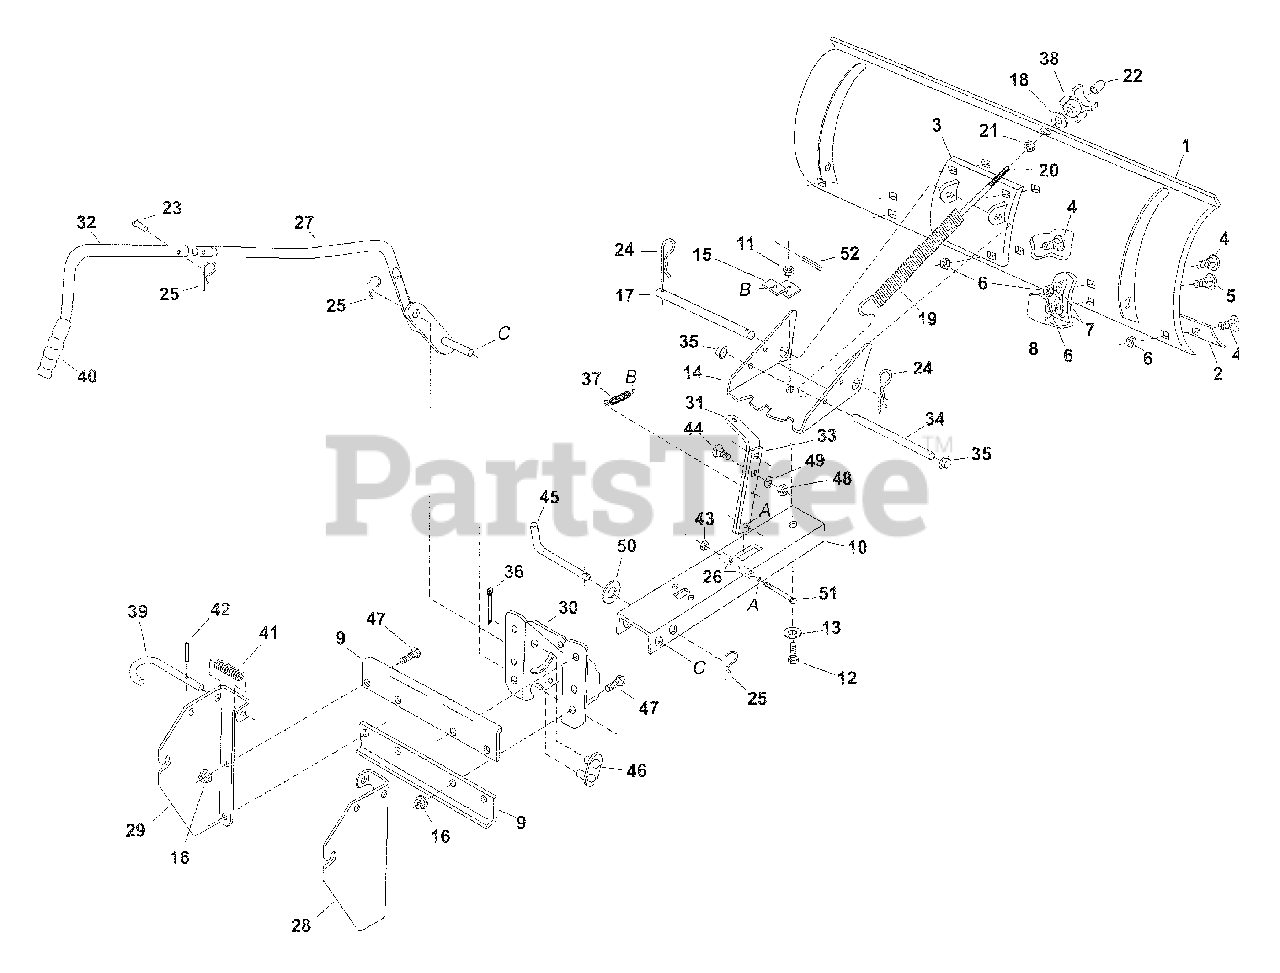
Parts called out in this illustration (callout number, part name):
1	Blade - 46"
2	Wear Plate - 46"
3	Reinforcement Plate Assembly
4	Bolt, Carriage 5/16-18 x 3/4"
5	Bolt, Carriage 5/16-18 x 1"
6	Hex Lock Nut, 5/16-18 Thread
7	Washer, 5/16"
8	Skid Shoe
9	Bracket, Angle Support
10	Push Channel
11	Hex Lock Nut, 1/2-13 Thread
12	Bolt, Special Pivot
13	Washer, Flat 1/2"
14	Plate, Pivot 7 Ga.
15	Bracket, Spring Mt.
16	Flanged Lock Nut, 3/8-16 Thread
17	Shaft, Pivot
18	Washer, 3/8" STD.
19	Spring, Blade Adjust
20	Hex Bolt, 3/8-16 x 3-1/2"
21	Hex Nut, 3/8-16 Thread
22	Plastic Cap
23	Pin, Clevis 1/4" x 1-1/2"
24	Pin, Hair Cotter #4 (1/8")
25	Pin, Hair Cotter #3 (3/32")
26	Spacer, .28 ID x 1"
27	Lift Handle Assembly, Lower
28	Hitch Bracket, R.H.
29	Hitch Bracket, L.H.
31	Angle Lock Bar (Long)
32	Lift Handle, Upper
33	Angle Lock Bar (Short)
34	Spring Mount Rod
35	Palnut, 3/8"
36	Cotter Pin 1/8" x 1"
37	Angle Lock Spring
39	Pin, Attachment
40	Handle, Grip
41	Spring, Compression
42	Pin, Spring 3/16" x 1"
43	Hex Lock Nut, 1/4-20 Thread
44	Carriage Bolt, 3/8-16 x 1-1/4"
45	Channel Pivot Pin
46	Lift Link Assembly
47	Hex Bolt, 3/8-16 x 1"
48	Hex Lock Nut, 3/8-16 Thread
49	Lock Washer 3/8"
51	Hex Bolt, 1/4-20 x 3-1/4" Lg. Gr 5
52	1/4" x 1" Spring Pin
